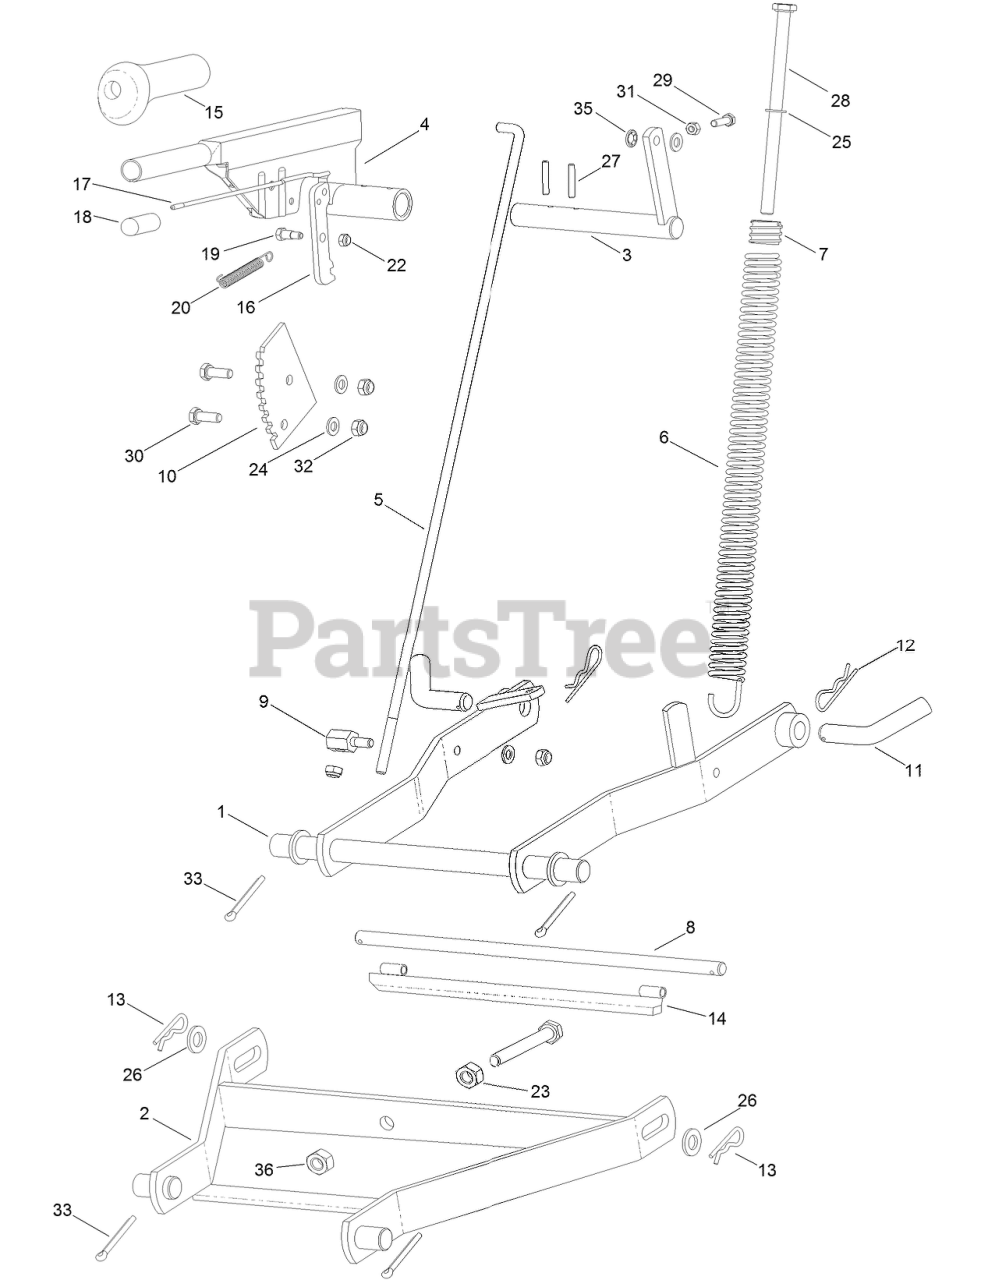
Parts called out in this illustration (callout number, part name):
1	SUSPENSION-DECK, MOWER
2	SUSPENSION-MOWER DECK, FRONT
3	SHAFT-ADJUSTMENT, HEIGHT
4	LEVER-ARM, HEIGHT ADJUST
5	ROD-ADJUSTMENT, HEIGHT
6	SPRING
7	NUT-SPRING
9	TRUNNION
10	SEGMENT-GEAR
11	PIN-BENT
12	PIN-HAIR
13	PIN-HAIR
14	HOLDER-FRONT
15	GRIP-HANDLE
16	RATCHET-PLATE, PIVOT
17	ROD-CONNECTION
18	BUTTON-PLUNGER
19	SCREW-LEVER
20	SPRING
22	NUT-LOCK
23	NUT-HEX
24	WASHER-PLAIN
25	WASHER-FLAT
26	WASHER-FLAT
27	PIN-SPRING
28	SCREW M10X180
29	SCREW-HH
30	SCREW-HH
31	NUT-HEX
32	NUT-LOCK, NI
33	PIN-COTTER
35	WASHER
36	NUT-LOCK, HEX NI
